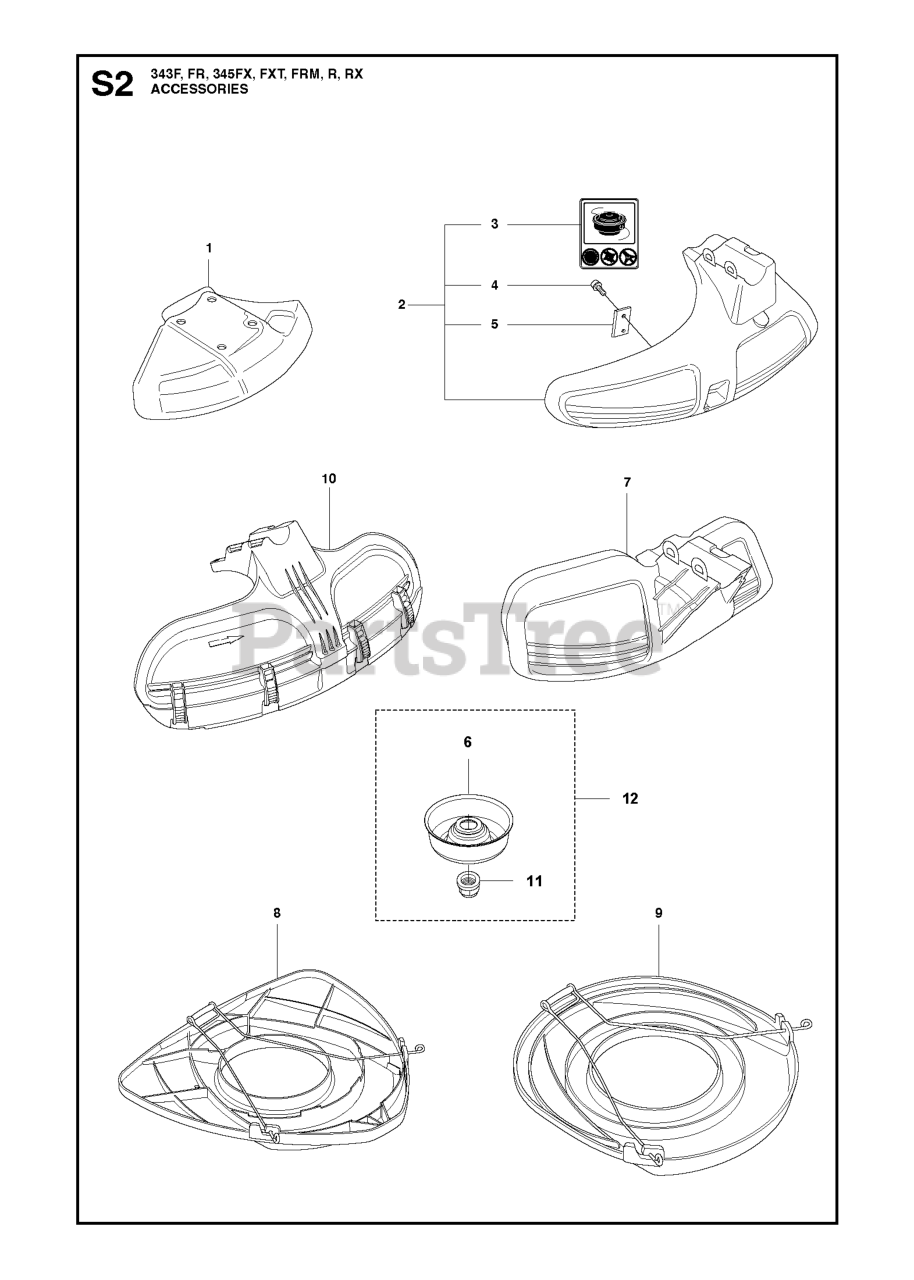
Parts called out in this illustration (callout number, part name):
1	BLADE GUARD SAW
1	RP BLADE GUARD
2	BLADE GUARD
5	LINE CUTTER
6	SUPPORT CUP
7	BLADE GUARD
8	TRANSPORT GUARD
9	BLADE GUARD TRANSPORT
10	COMBINATION GUARD
